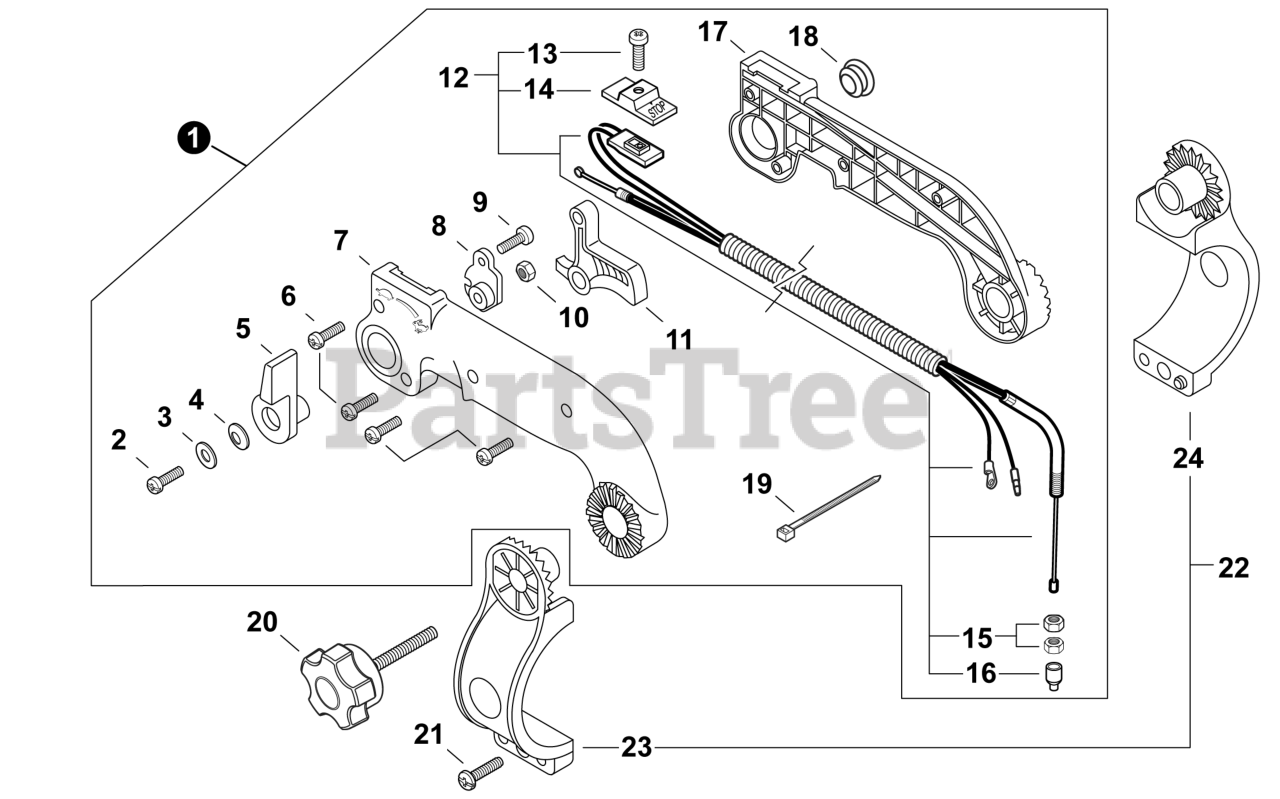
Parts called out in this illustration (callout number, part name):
1	THROTTLE CONTROL KIT - TUBE MOUNT
2	SCREW 6x20
3	WASHER, SPRING 6
4	WASHER 6.5x13x1
5	CONTROL, THROTTLE
6	SCREW 4x22
7	CONTROL HANDLE - LEFT
8	BRACKET, THROTTLE
9	SCREW 4x10
10	NUT, HEX M6
11	TRIGGER, THROTTLE
12	CABLE ASSY, CONTROL
13	SCREW 3x10
14	KNOB, SWITCH - RED
15	NUT 6 MM
16	CAP, DUST
17	CONTROL HANDLE - RIGHT
19	STRAP, CABLE
20	KNOB, SCREW
21	SCREW, TAPPING 5x20
22	BRACKET KIT, HANDLE
23	BRACKET, HANDLE - LEFT
24	BRACKET, HANDLE - RIGHT
